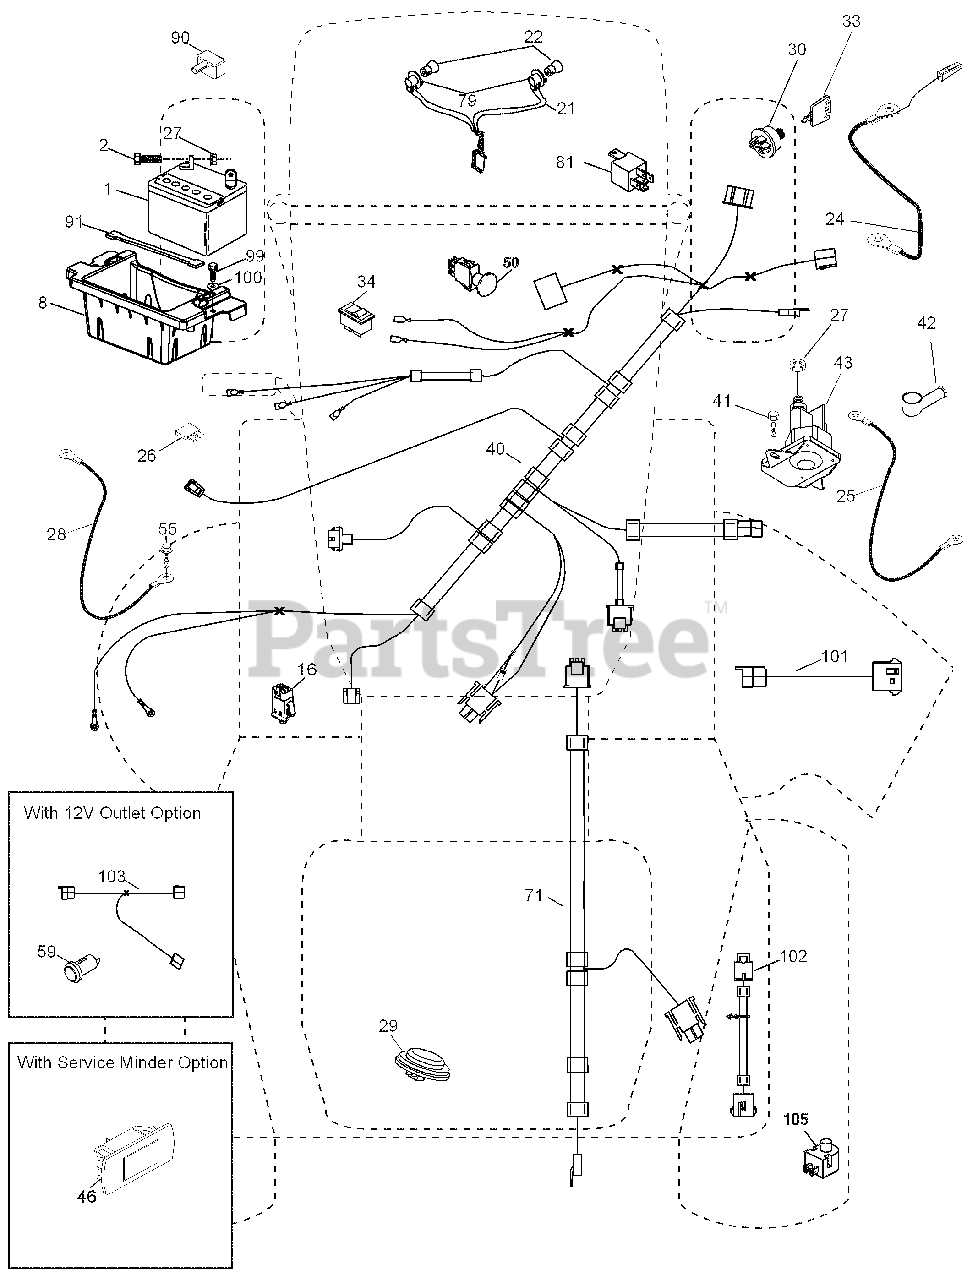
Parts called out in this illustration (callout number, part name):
1	Battery
2	Bolt Hex Head 1/4-20 x 3/4
8	Box Battery
16	Switch Interlock Push-In
21	Harness Socket Light w/4152J
22	Bulb Light
24	Cable Battery 8"
25	Cable Starter
27	Nut Keps Hex 1/4-20 unc
28	Cable, Ground
29	Switch, Seat
30	Switch, Ign
34	Switch Light/Reset
40	Harness Ign. Dash
41	Screw Thd Cut 1/4-20 x 1/2
42	Cover, Terminal
43	Solenoid
46	Gauge Service Reminder Hrmtr
50	Switch PTO
55	Screw Thdrol 5/16-18 x 3/4 TYTT
59	Outlet 12-Volt
71	Harness Ign.
79	Socket Asm Bulb Twistlock
81	Relay Harness Sealed
90	Cover Terminal
91	Strap Battery Mount
99	Screw 1/4-20 x 3/4
100	Washer 9/32 x 7/8 x 16 Ga.
101	Harness Pigtail
102	Harness Pigtail
103	Harness 12-Volt Pigtail
105	Switch Reverse TT Pedal Control
